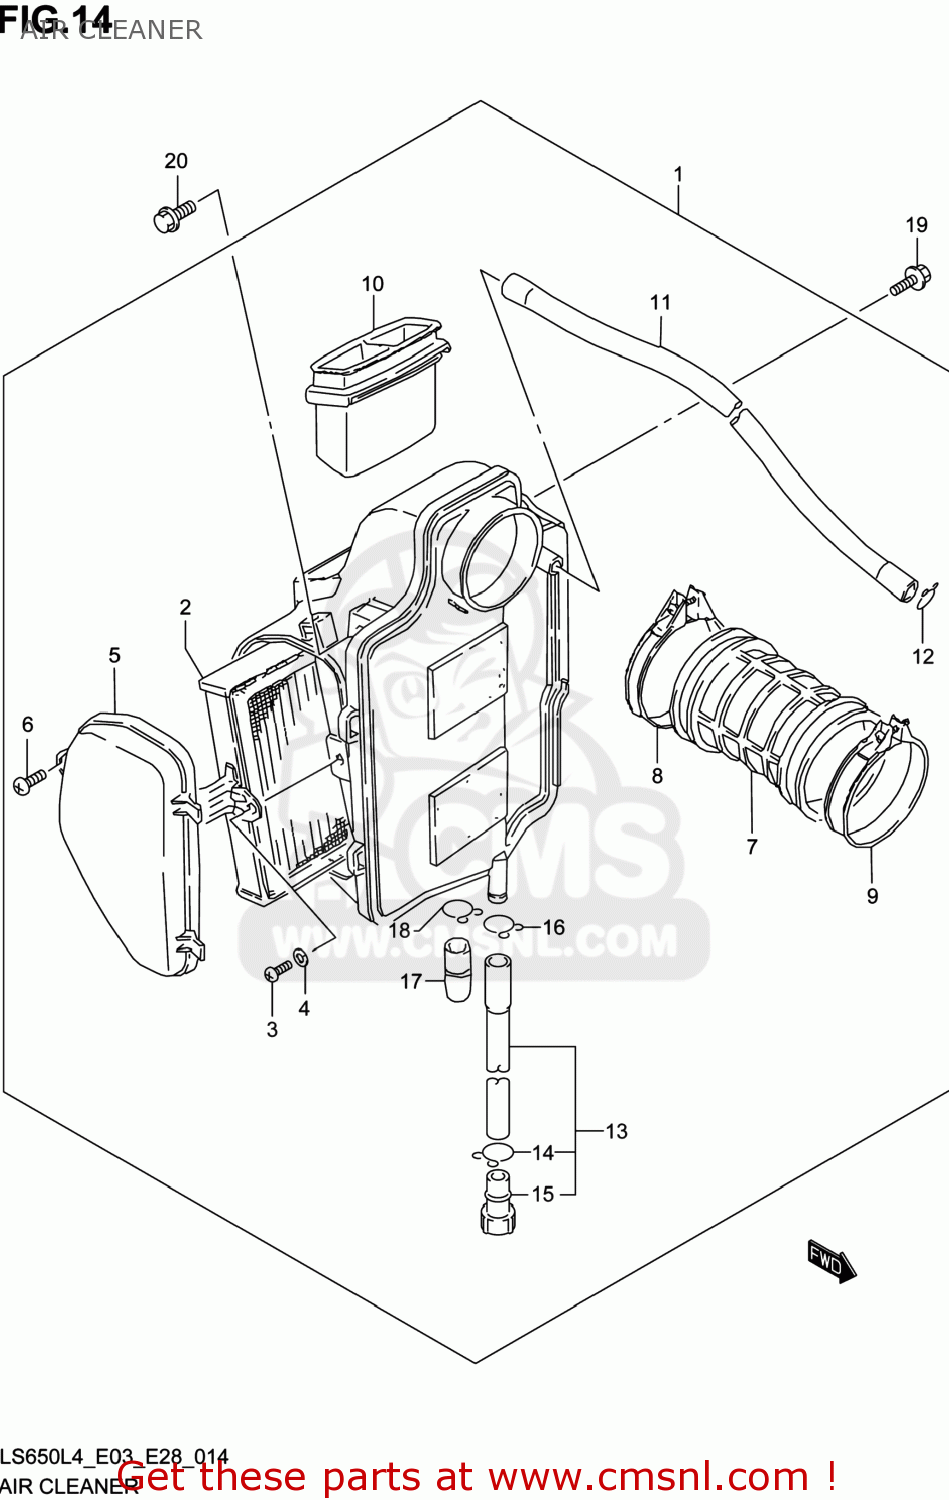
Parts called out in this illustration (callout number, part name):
1	CLEANER ASSY,AIR
2	FILTER ASSY,AIR
3	SCREW
4	WASHER,LOCK
5	CAP,AIR CLEANER
6	SCREW
7	TUBE,AIR CLEANER OUTLET
8	CLAMP
9	CLAMP
10	TUBE,INLET
11	HOSE(11X15X600)
12	CLIP
13	TUBE,DRAIN
14	CLIP
15	STOPPER,DRAIN
16	CLIP
17	PLUG
18	CLIP
19	BOLT(6X16)
20	BOLT
